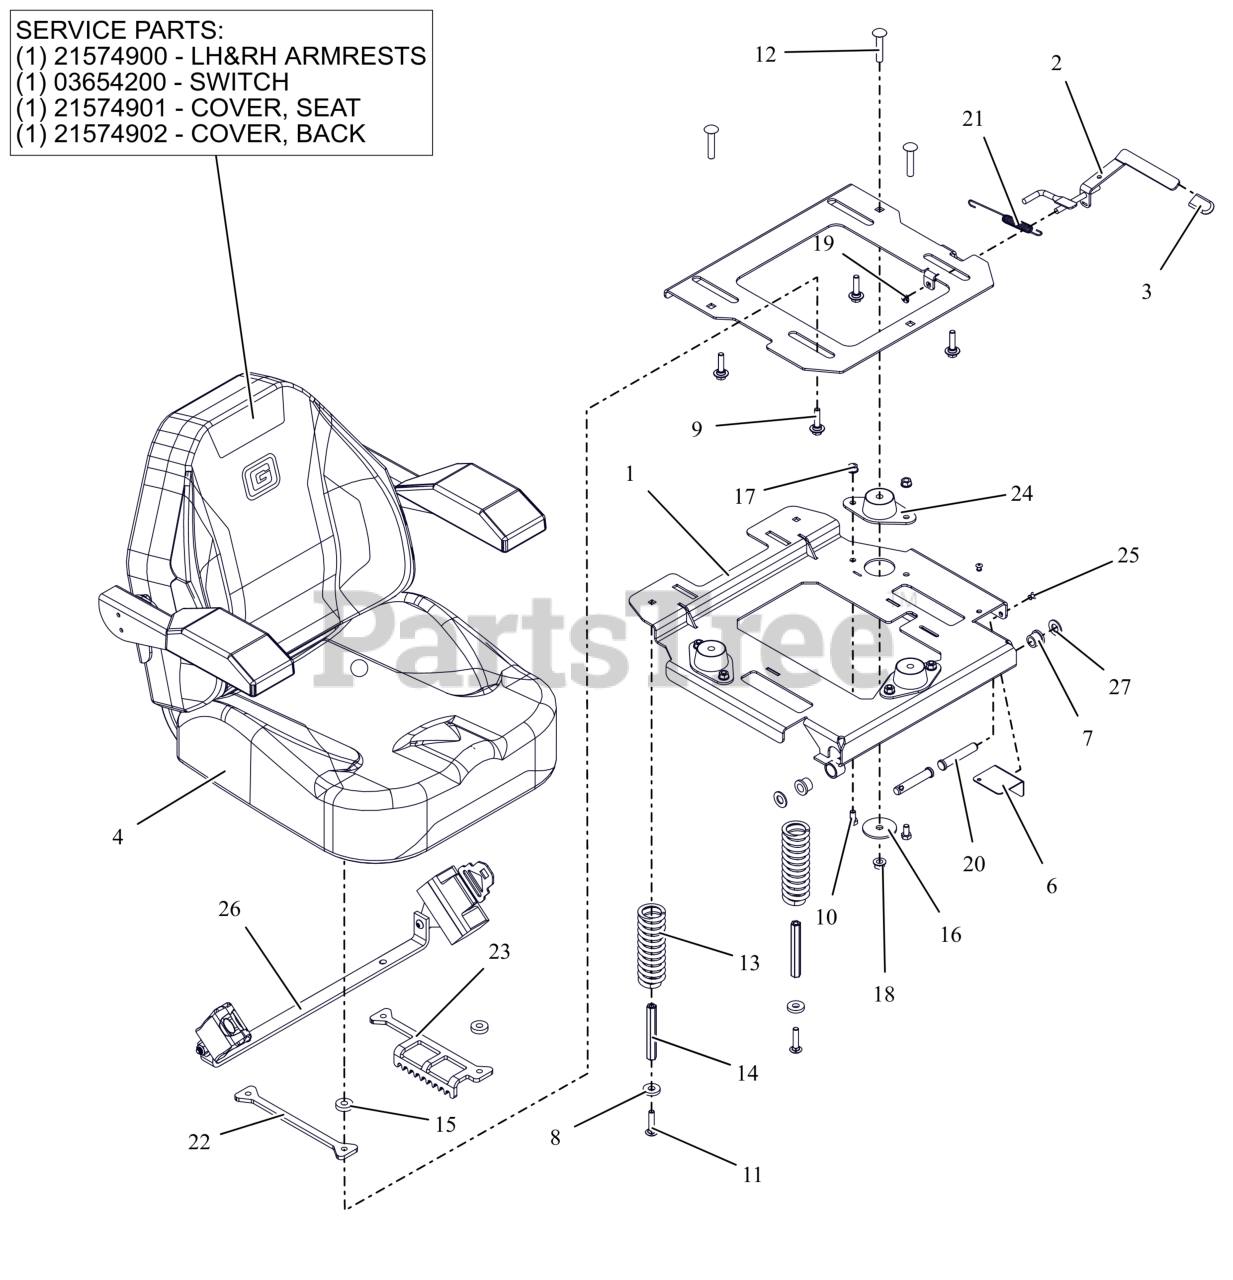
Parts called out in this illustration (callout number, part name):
1	WLDMT- ISO MTG PLATE 3PT
2	WLDMT, SEAT SLIDE LEVER
3	GRIP, SEAT LEVER, GREY
4	SEAT, HD
4	LH&RH ARMRESTS
4	SWITCH- SEAT
4	COVER, SEAT - HD
4	SEAT COVER, BACK HD
5	PLATE- SEAT MTG 3PT (ISO KIT)
6	GUARD, SEAT FAN (SH)(BLACK)
7	BSHG, FLG .516X.750X.625X.937
8	WSHR, FLT .406X1.00X.188 ZCC
9	BLT, SHLDR .31-18 X .175
10	BLT, HEX .31-18X.625 G5 ZCC
11	BLT,RHSN .31-18X1.50 G5 ZCC
12	BLT,RHSSN.375-16X2.00 G5 ZCC
13	SPRING, COMPRESSION SEAT 224LB
14	NUT, COUPLING 5/16X18 X 3.75
15	WSHR, FLT .390X1.00X.250 ZCC
16	WSHR-FL-STL 0.406X2X0.125 ZCC
17	NUT,LK-CTR-FLG .31-18 GF ZCC
18	NUT-LK-CTR-FLG .375-16 GF ZCC
19	NUT-PUSH .312
20	PIN, SLIC-.500X42.70X2.31 -ZC
21	SG-TENS .06X.482X5.35
22	PLATE, ADJ SEAT SLIDE (BLACK)
23	PLATE, SEAT ADJ (BLACK)
24	MOUNT- FAIL-SAFE COMPRESSION
25	RIVET, .1875 AL/AL .126-.250
26	KIT-SEAT BELT REPLACE-05007300
27	WSHR-FL-NYL .518X1.000X.080
